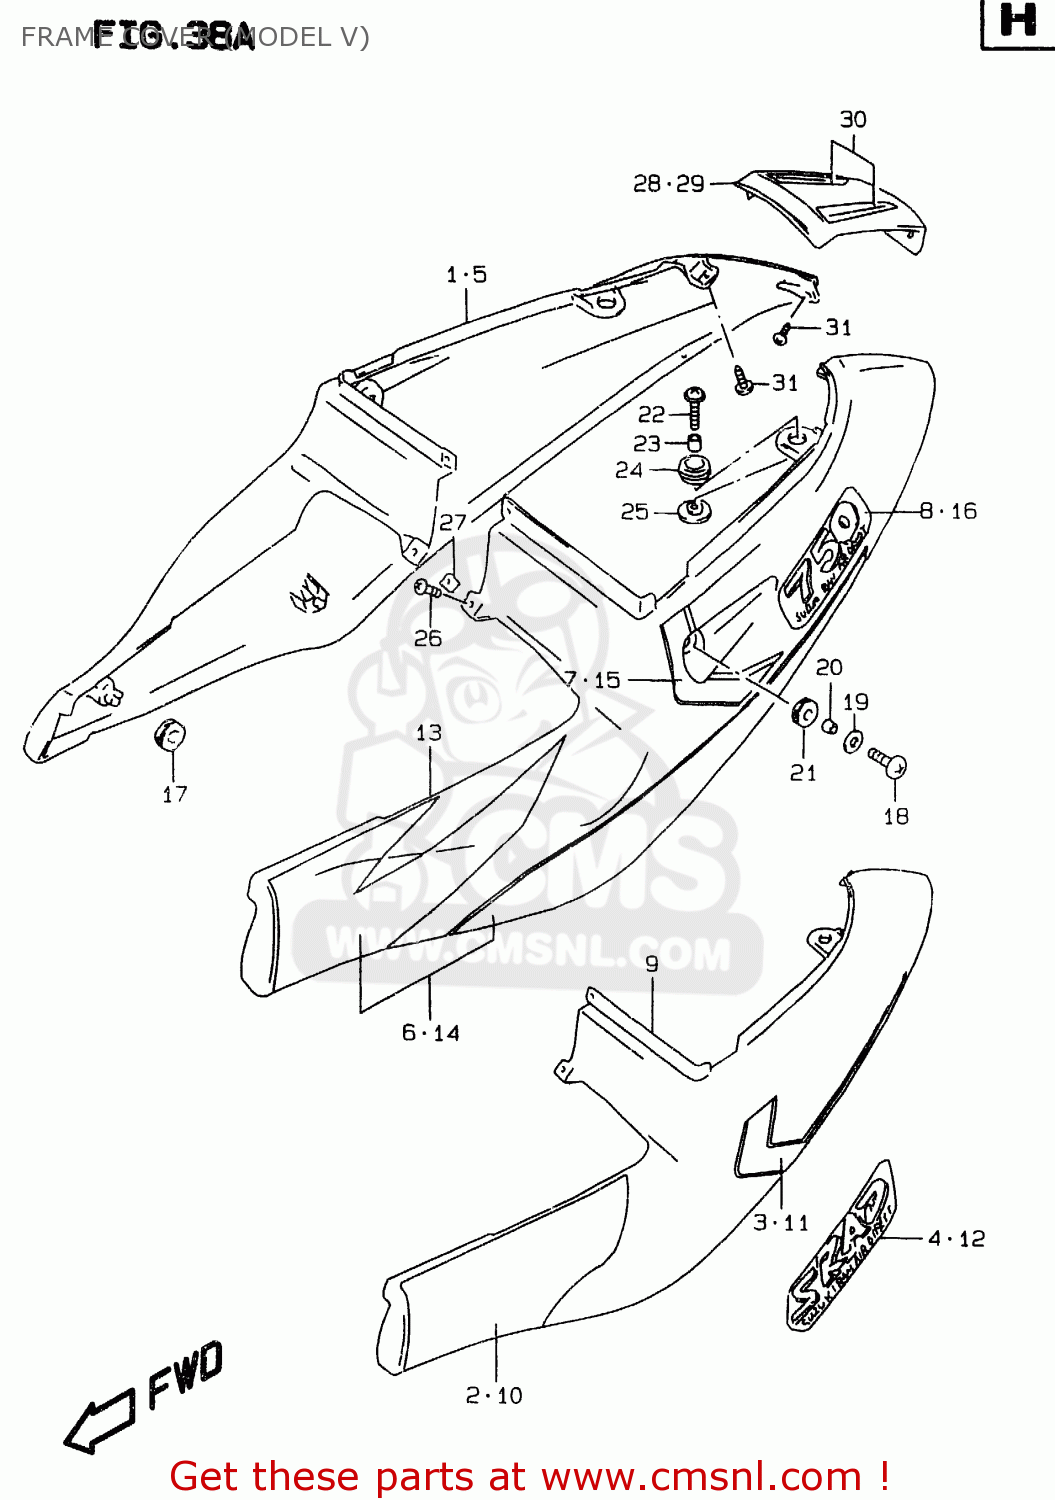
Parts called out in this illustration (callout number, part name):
1	COVER,FRAME,R(ORANGE)
2	TAPE,FRAME COVER,R(GRAY)
3	TAPE,FRAME COVER STRIPE
4	EMBLEM,FRAME COVER
5	COVER,FRAME,R(WHITE)
6	TAPE SET,FRAME COVER,R
7	TAPE,FRAME COVER,R
8	EMBLEM,FRAME COVER
9	COVER,FRAME,L(ORANGE)
10	TAPE,FRAME COVER,L(GRAY)
11	TAPE,FRAME COVER STRIPE,L
12	EMBLEM,FRAME COVER
13	COVER,FRAME,L(WHITE)
14	TAPE SET,FRAME COVER,L
15	TAPE,FRAME COVER,LEFT
16	EMBLEM,FRAME COVER
17	CUSHION
18	SCREW(6X20)
19	WASHER(6.5X22X1.6)
20	SPACER(6.5X9X6.7)
21	CUSHION
22	SCREW(6X25)
23	SPACER(6.5X10X9.4)
24	CUSHION,TAIL COVER UPR
25	CUSHION,FRAME COVER LWR
26	SCREW
27	NUT
28	COVER,FRAME CTR
29	COVER,FRAME CTR
30	TAPE SET,FRAME COVER CTR
31	SCREW
